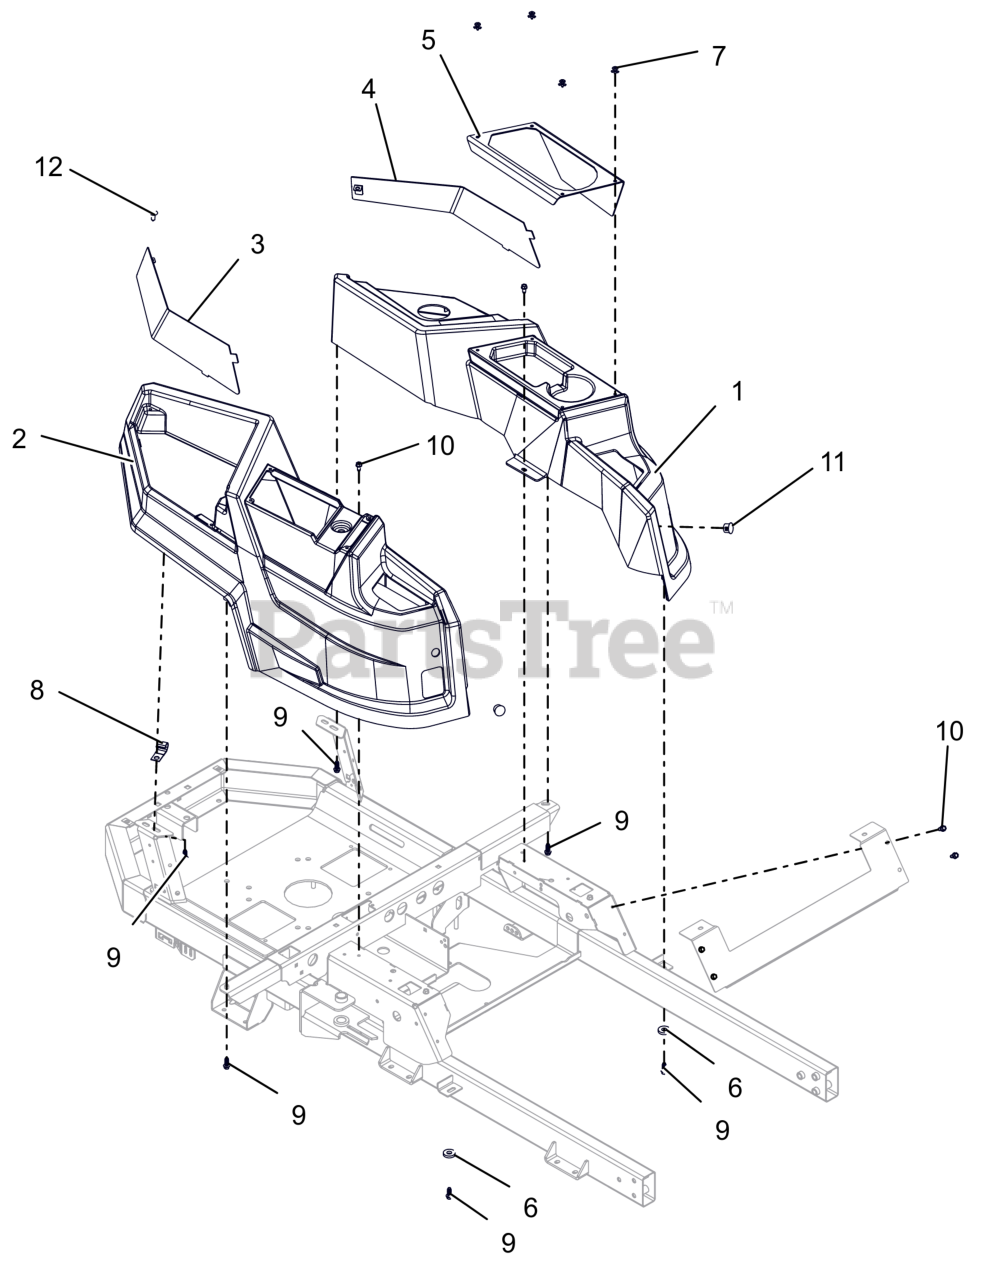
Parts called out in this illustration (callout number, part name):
1	FENDER, LH -ZOOM
2	FENDER, RH -ZOOM
3	WLMT, FENDER BLOCKOFF-RH
4	WLMT, FENDER BLOCKOFF-LH
5	PANEL, CUPHOLDER/STORAGE (LH)
6	WSHR, FLT .406X1.00X.188 ZCC
7	RIVET, PLASTIC .195 DIA.
9	SCR-.312X.75 #14H H/W/H H/L CZ
10	SCR-TAP .25-20X.50 HWH ZCC
11	PLUG, HOLE .75 (BLACK)
12	XMAS TREE FASTNER-BLACK
